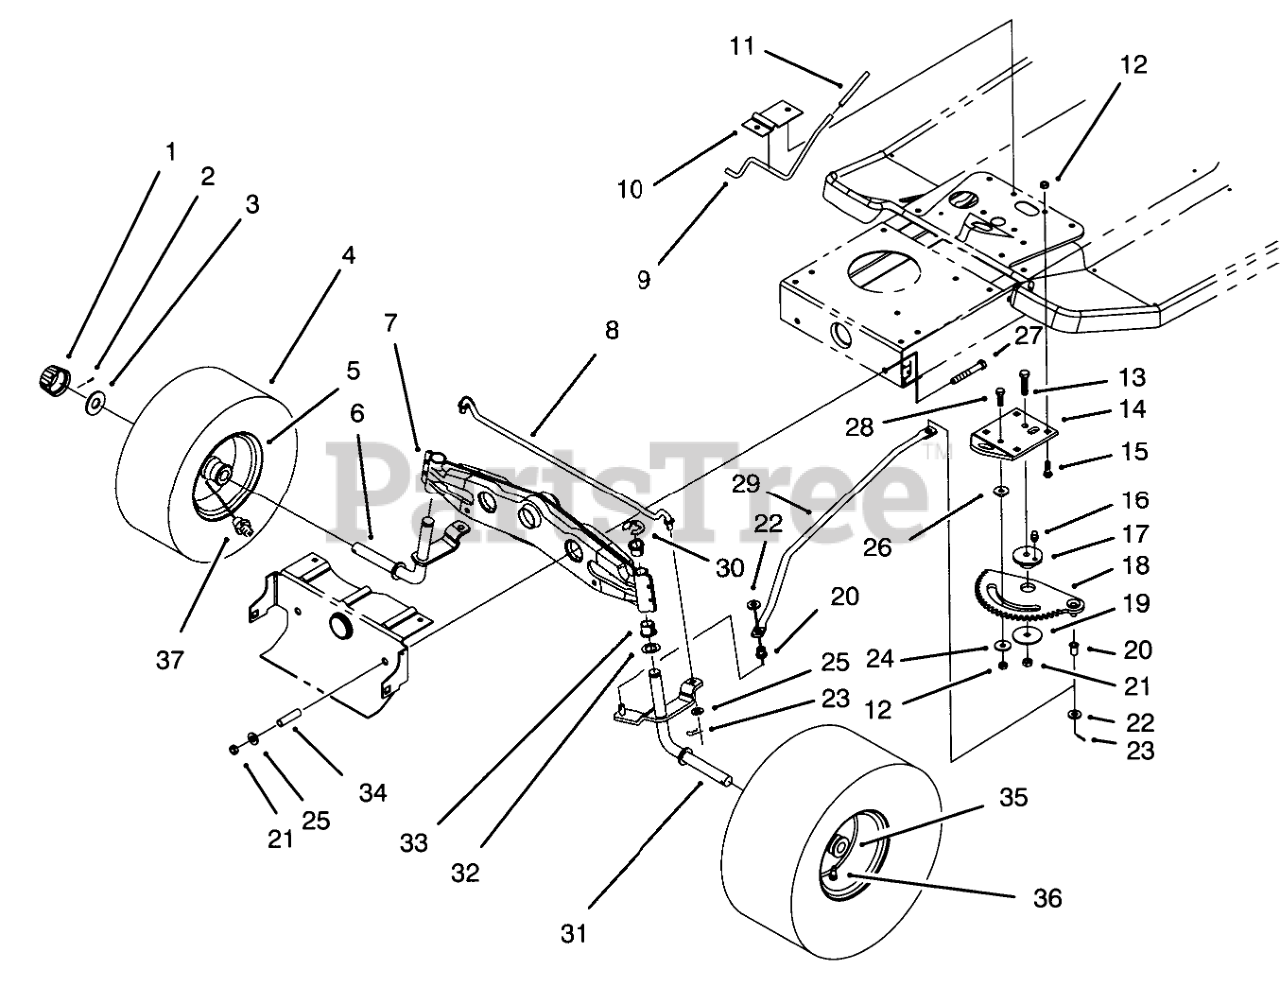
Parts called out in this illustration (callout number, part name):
1	CAP-HUB
2	PIN-COTTER
3	WASHER-PLAIN
4	TIRE 13 X 5.00 X 6
5	RIM ASM
6	Spindle-R.H.
7	Axle-Front
8	TIE ROD-STEERING
9	ROD-BRAKE, PARKING
10	Bracket-Parking Brake
11	GRIP-BRAKE, PARKING
12	NUT-LOCK, NI
13	SCREW-CARR
14	Bracket-Steering Rack
15	BOLT-CARR
16	FITTING-GREASE
17	BUSHING-ECCENTRIC
18	RACK-STEERING
19	WASHER-BEARING
20	BUSHING-FLANGED, NYLON
21	NUT-LOCK, NI
22	WASHER-FLAT
23	PIN-COTTER
24	WASHER-PIVOT
25	WASHER-FLAT
26	SPACER-RACK, STEERING
27	SCREW-HH
28	SCREW-CARR
29	LINK-DRAG
30	E-RING
31	Spindle-L.H.
32	WASHER-THRUST
33	BUSHING
34	SPACER
35	BEARING-WHEEL
36	STEM-VALVE
37	FITTING-GREASE
